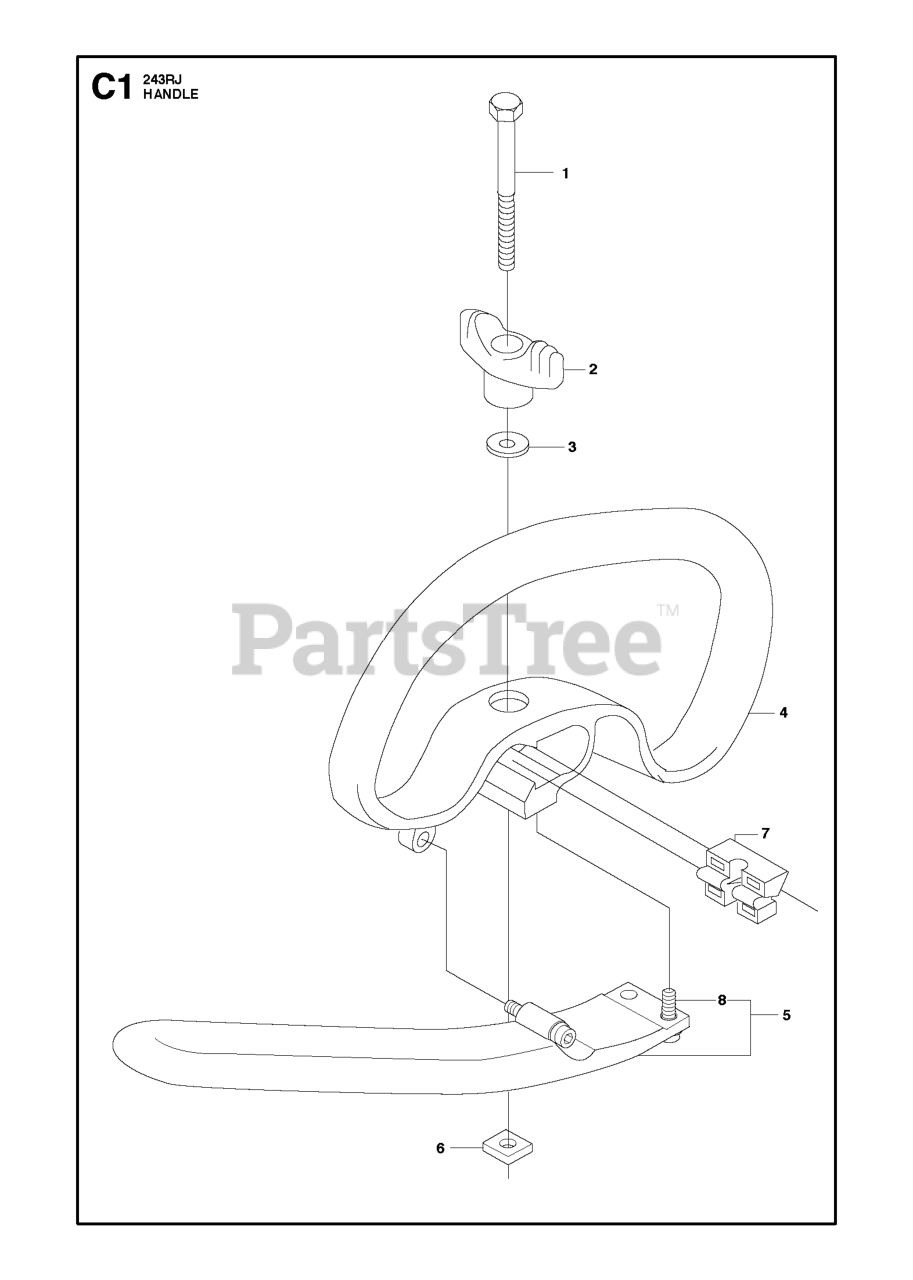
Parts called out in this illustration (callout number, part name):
1	SCREW M6X50
4	HANDLE.LOOP
5	HANDLE EXTENSION
8	SCREW IHSCFTO
